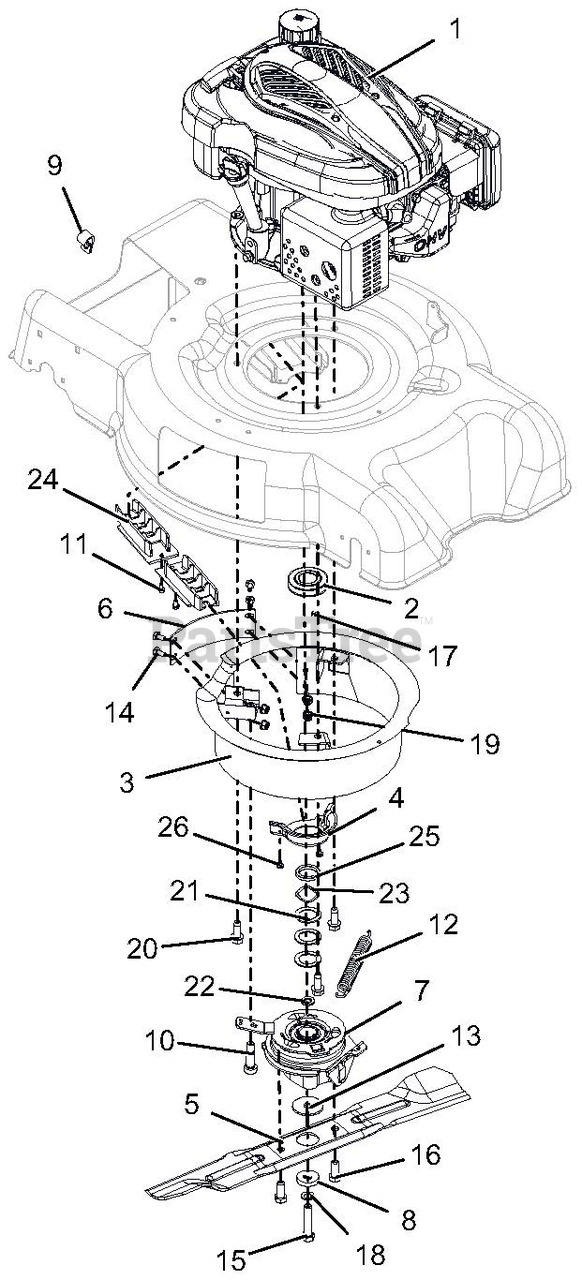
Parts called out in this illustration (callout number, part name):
1	ENGINE, LONCIN 159CC VERT. BBC
2	PULLEY,MACHINED POWDER METAL
3	WLDMT, ENCLOSURE - BBC
4	GUIDE, BELT CRANK
5	BLADE, MOWER 21" HIGH LIFT-BBC
6	BAFFLE, BBC
7	CLUTCH, RAZOR/XD3, 25MM
8	WSHR-FL-STL .44X1.25X.25 YWZC
9	CLAMP, LM CABLE
10	BLT,SHLDR 12MM X 25 W/ M10 THD
11	SCR-TAP 10-24X.375 PRE-COAT 80
12	SPRING, EXTENSION BBC
13	WSHR-FL-STL .469X1.75X.10 YWZC
14	@BLT-HEX .25-20X.50 GR5 YWZC
15	BLT-HEX .44-20X2.00 GR5 YWZC
16	BLT-HEX M10 X 1.5X25 YWZC
17	KEY-SQ .188X.188X.250
18	WSHR-FL-STL .45X.75X.033
19	@NUT-LK-TOP-FLG .25-20 YWZC
20	@SCR-TAP .38-16X1.00 HWH TR YZ
21	WSHR-FL-STL 1.010X1.505X.062YZ
22	WSHR-FL-STL .459X.750X.105 YZC
23	WASHER - WAVE 1.09X1.37X.016
24	GUIDE, BELT INNER
25	SPCR, 1.00 X 1.375 X .179
26	SCR-TAP 10-24X.25 CRSLPH TR YZ
